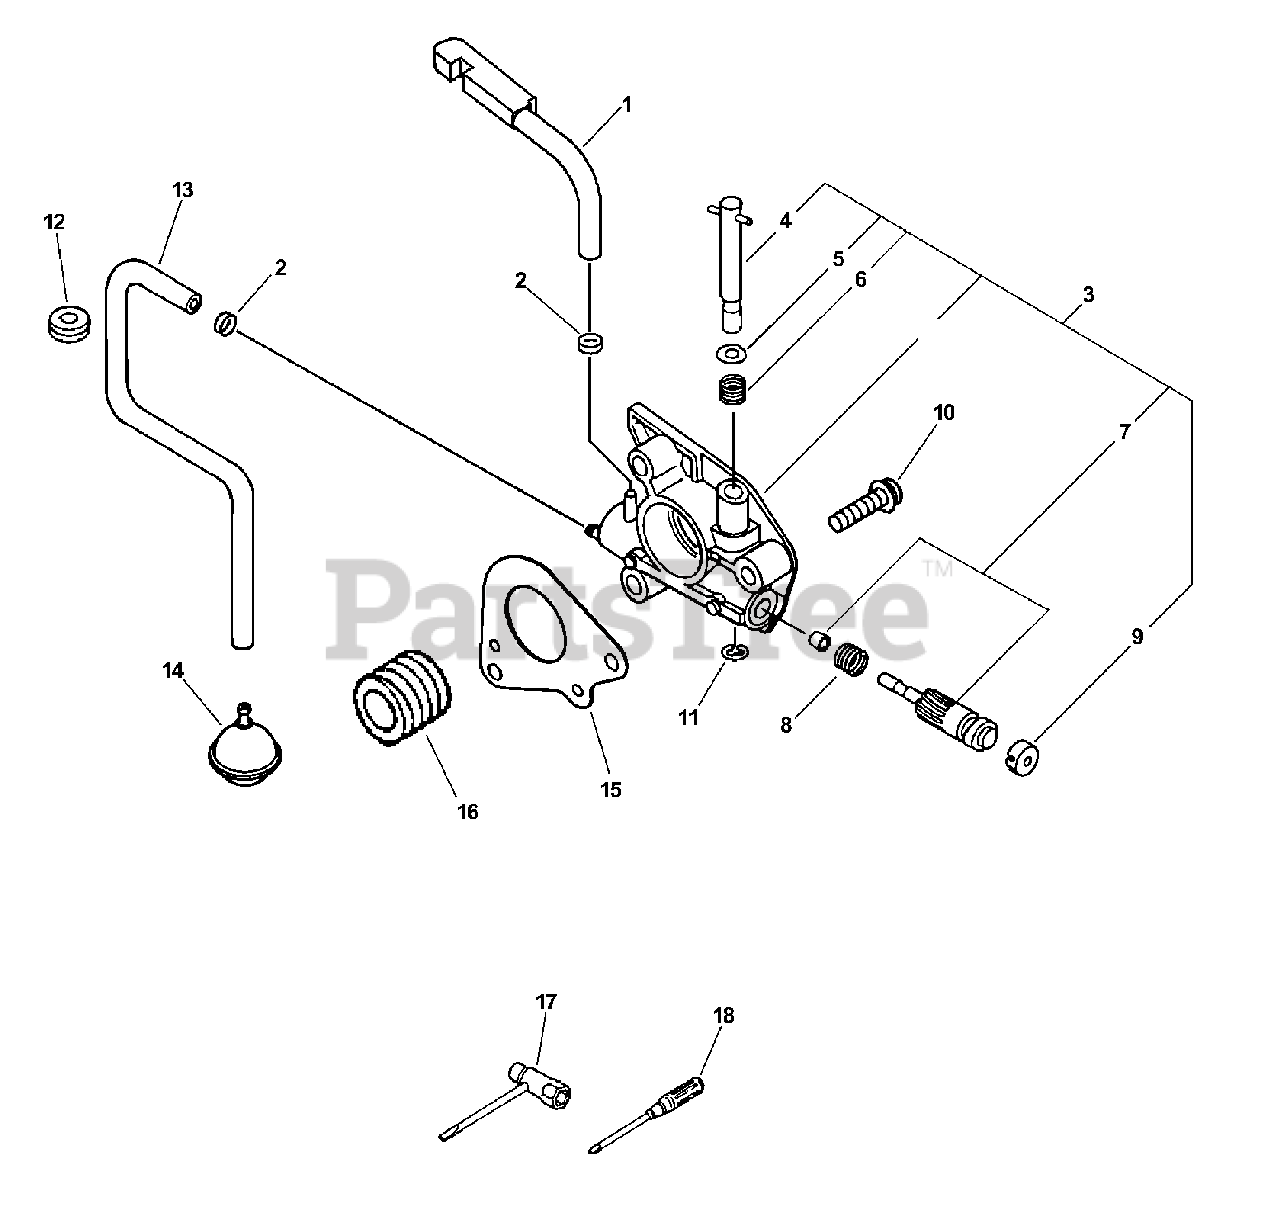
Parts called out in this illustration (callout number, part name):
1	PIPE, OIL OUTLET
2	CLIP Ø6.5 MM
3	AUTO-OILER ASSY
4	SCREW, ADJUSTER
7	PLUNGER ASSY
9	CAP, OIL PUMP
10	SCREW 4×16
13	PIPE, OIL
14	FILTER, OIL
15	PLATE, SEAL
16	GEAR, WORM
17	T-WRENCH 13×19×180
18	SCREWDRIVER, PHILLIPS
